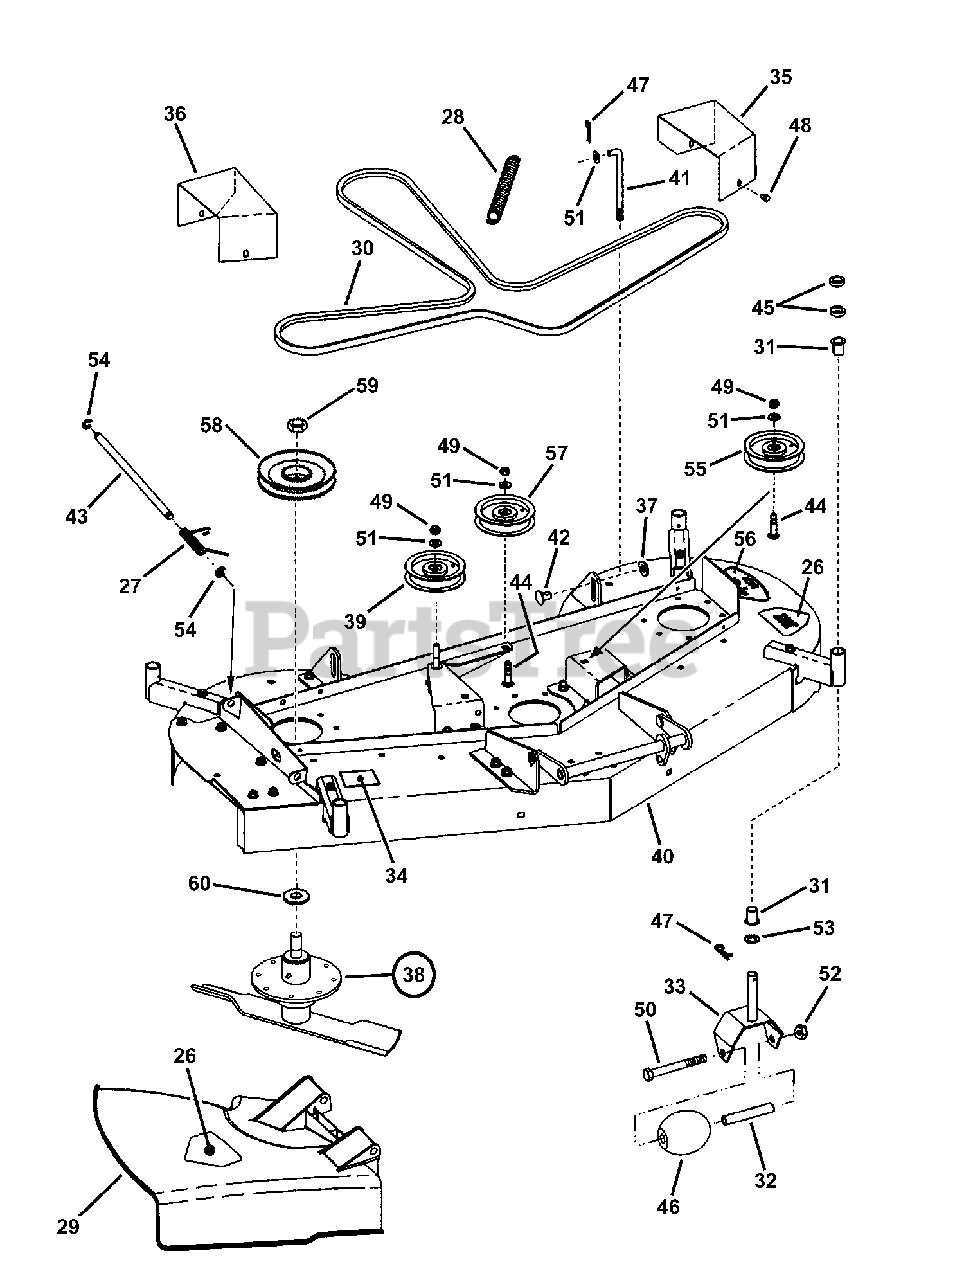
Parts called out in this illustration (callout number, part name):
26	DECAL, Danger, Cut Finger
27	SPRING, Torsion
28	SPRING, Extension, 48" HOZ
29	DISCHARGE CHUTE, Hi Impact Co-Polymer
30	V-BELT, HA Sect., 120.722" effective length
31	BUSHING, Flange, .64 x .75 x .5
32	SLEEVE, Caster Wheel
33	WELDMENT, Pivot Yoke, Caster
34	DECAL, Chute/Deflector
35	COVER, Belt, LH
36	COVER, Belt, RH
37	WASHER, 1/2" Flat
38	ASSEMBLY, 48" Spindle
39	PULLEY, 3-1/4 Dia. Flat Idler
40	*ASSEMBLY, 48" Painted Mower Deck
41	LINK, Leveling (3/8-16 thread)
42	SWIVEL, Support (3/8-16 internal thread)
43	HINGE PIN
44	BOLT, 3/8-16 x 1-3/4" Short Neck Carriage, GR 5
45	SPACER, Blade
46	ROLLER, Low Density Polyethylene
47	HAIR PIN, 3/32 x 1-1/2"
48	SCREW, 1/4-20 x 3/8" Hex Washer Self Tap
49	NUT, 3/8-16 Hex Center Lock
50	SCREW, 1/2-20 x 4-1/2" Hex Head Cap, GR 5
51	WASHER, 3/8" SAE Flat
52	NUT, 1/2-20 Hex Center Lock, GR 5 or B
53	WASHER, .64 x .99 x .05 Flat
54	RING, .392 External Retaining
55	IDLER, 4.12" Outside Diameter, Flat
56	DECAL, 48" Deck
57	PULLEY, 5" x .375 Flat Idler (Belt Clutch)
58	PULLEY, Driven, 4.50" O.D.
59	NUT, 3/4-16 Hex Jam, GR 8
60	WASHER, Spindle
